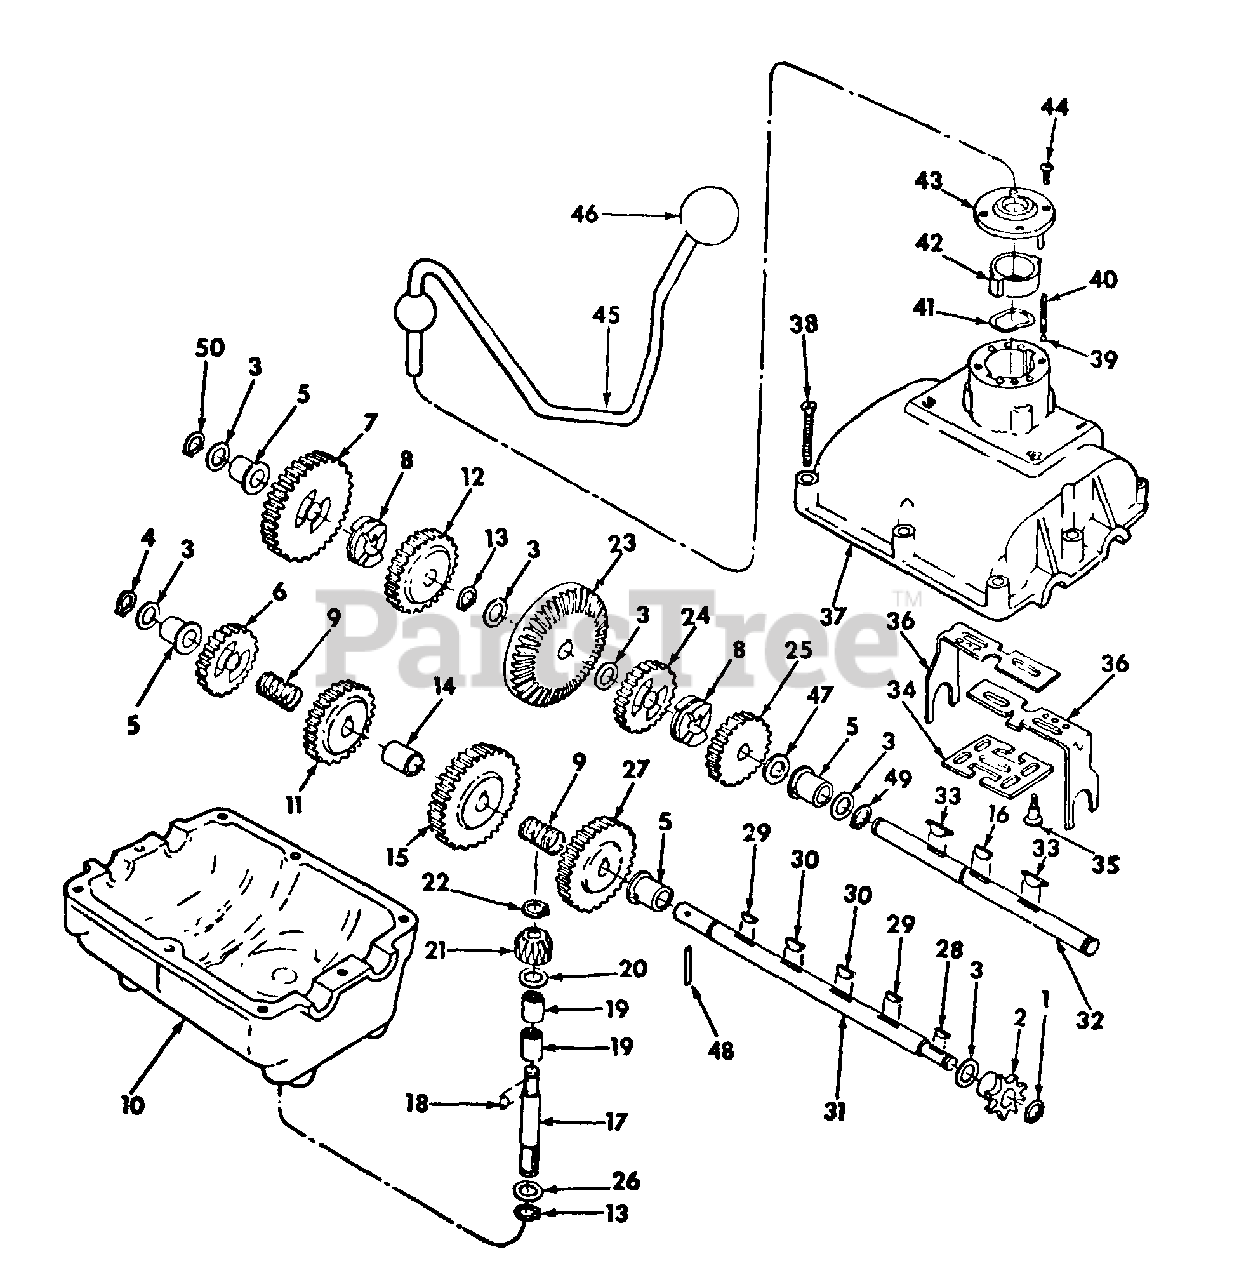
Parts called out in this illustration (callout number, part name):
1	RING, RETAINING 461 X .035
2	SPROCKET, 8 TEETH
3	WASHER, PLAIN .030
4	RING, RETAINING
5	BEARING, FLANGE
6	GEAR, SPUR - 20 TEETH
7	GEAR, SPUR - 30 TEETH
8	COLLAR, CLUTCH
9	SPRING, COMPRESSION
10	HOUSING, LOWER
11	GEAR, SPUR - 25 TEETH
12	GEAR, SPUR - 25 TEETH
13	RING, RETAINING
15	GEAR, SPUR - 30 TEETH
16	KEY, 3/16 X 3/4 WOODRUFF 9
17	SHAFT KIT, INPUT
18	KEY, 3/32 X 1/2 WOODRUFF 2
19	BEARING, NEEDLE
20	WASHER, THRUST .093
21	PINION, BEVEL - 16 TEETH
22	RING, RETAINING
23	GEAR, BEVEL - 42 TEETH
24	GEAR, SPUR - 20 TEETH
25	GEAR, SPUR - 22 TEETH
26	WASHER, PLAIN 21/32 X 1 X 16 GA
27	GEAR, SPUR - 28 TEETH
28	KEY, WOODRUFF NO. 4 SPECIAL
29	KEY, 1/8 X 1/2 WOODRUFF 3 ALLOY
30	KEY, 3/16 X 5/8 WOODRUFF 61 ALLOY
31	SHAFT, OUTPUT
32	SHAFT, DRIVE
33	KEY, HI-PRO SPECIAL
34	PLATE, LOCK-OUT
35	SCREW, SHOULDER
36	FORK, SHIFTER
37	HOUSING, UPPER
38	SCREW, TAPPING
39	BALL, 3/16 GRADE 25 METAL
40	SPRING, DETENT
41	WASHER, WAVE
42	INSERT, NYLON
43	COVER, NYLON
44	SCREW, 10-24 X 1/2 C-Z PAN-HD TAP
45	SHIFTER, HANDLE
46	KNOB, SHIFTER
47	WASHER, THRUST .093
48	PIN, 1/4 X 1-1/8 MED COILED SPRING
49	RING, RETAINING .048 X .042
50	RING, RETAINING .048 X .042
